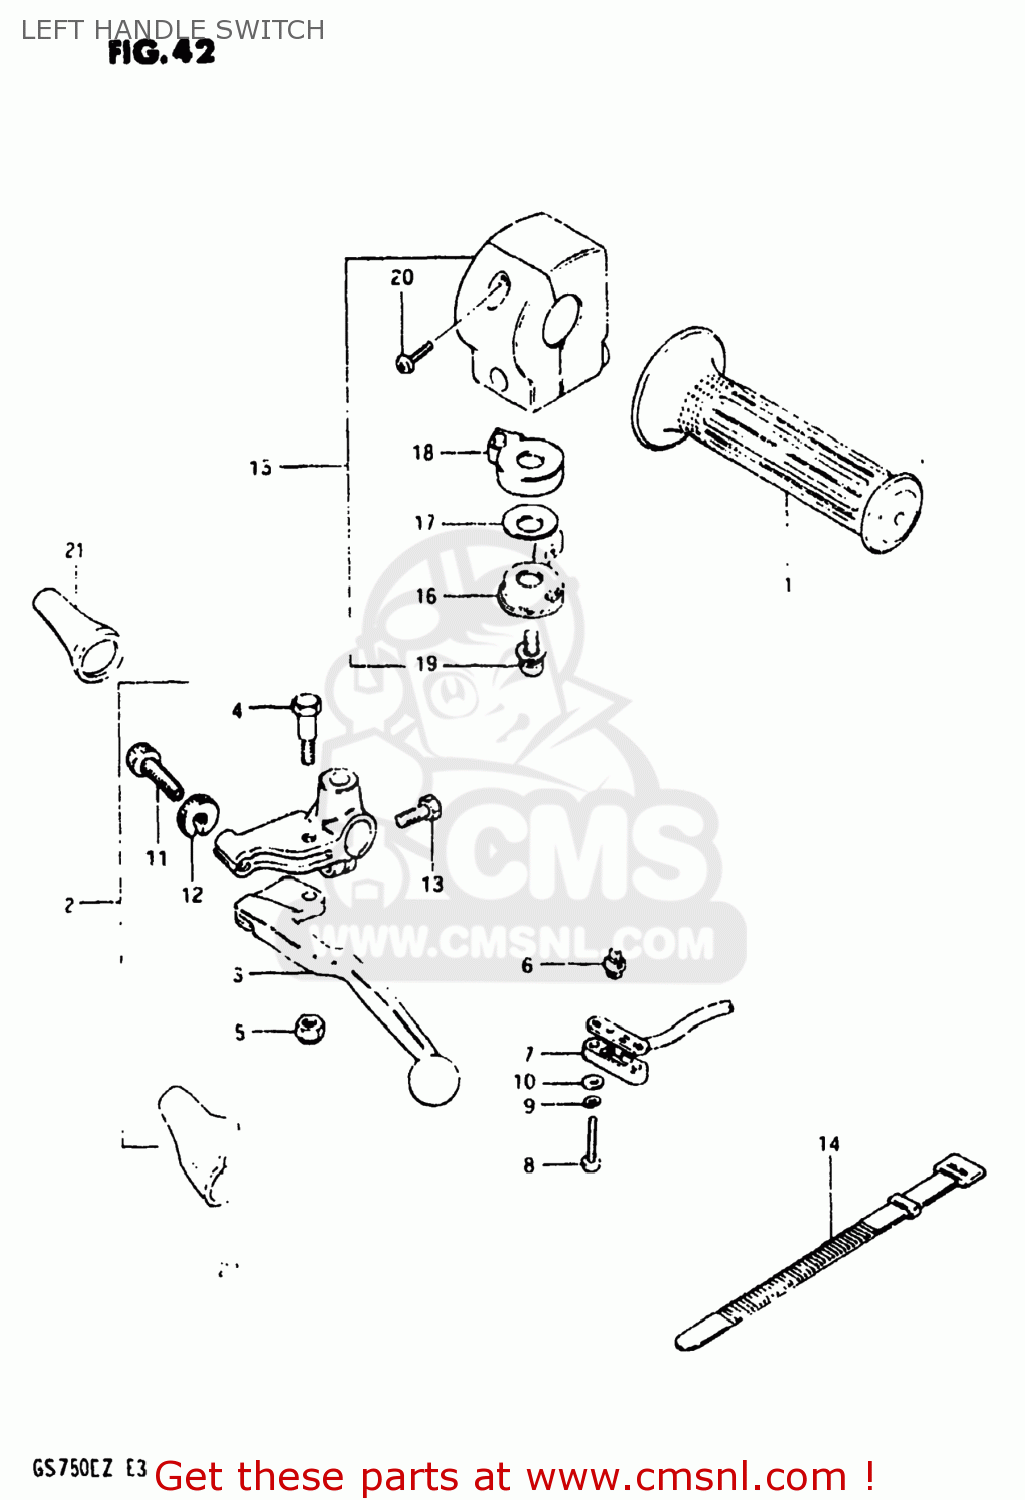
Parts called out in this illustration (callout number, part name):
1	GRIP,LEFT
2	LEVER ASSEMBLY
3	LEVER,CLUTCH
4	BOLT,LEVER
5	NUT 6MM
6	CONTACT,SWITCH
7	COVER,FR BK TERMINAL BASE
8	SCREW
9	LOCK WASHER
10	WASHER
11	ADJUSTER,CABLE
12	NUT,CABLE ADJUSTER
13	BOLT,CLUTCH LEVER HOLDER
14	CLAMP(L:120)
15	SWITCH ASSEMBLY,HANDLE,LEFT
16	LEVER,STARTER
17	WASHER,ADJUSTER
18	BODY,CHOCK
19	SCREW,CHOKE LE
20	SCREW
21	BOOT,CLUTCH CABLE
22	COVER,CLUTCH LEVER
